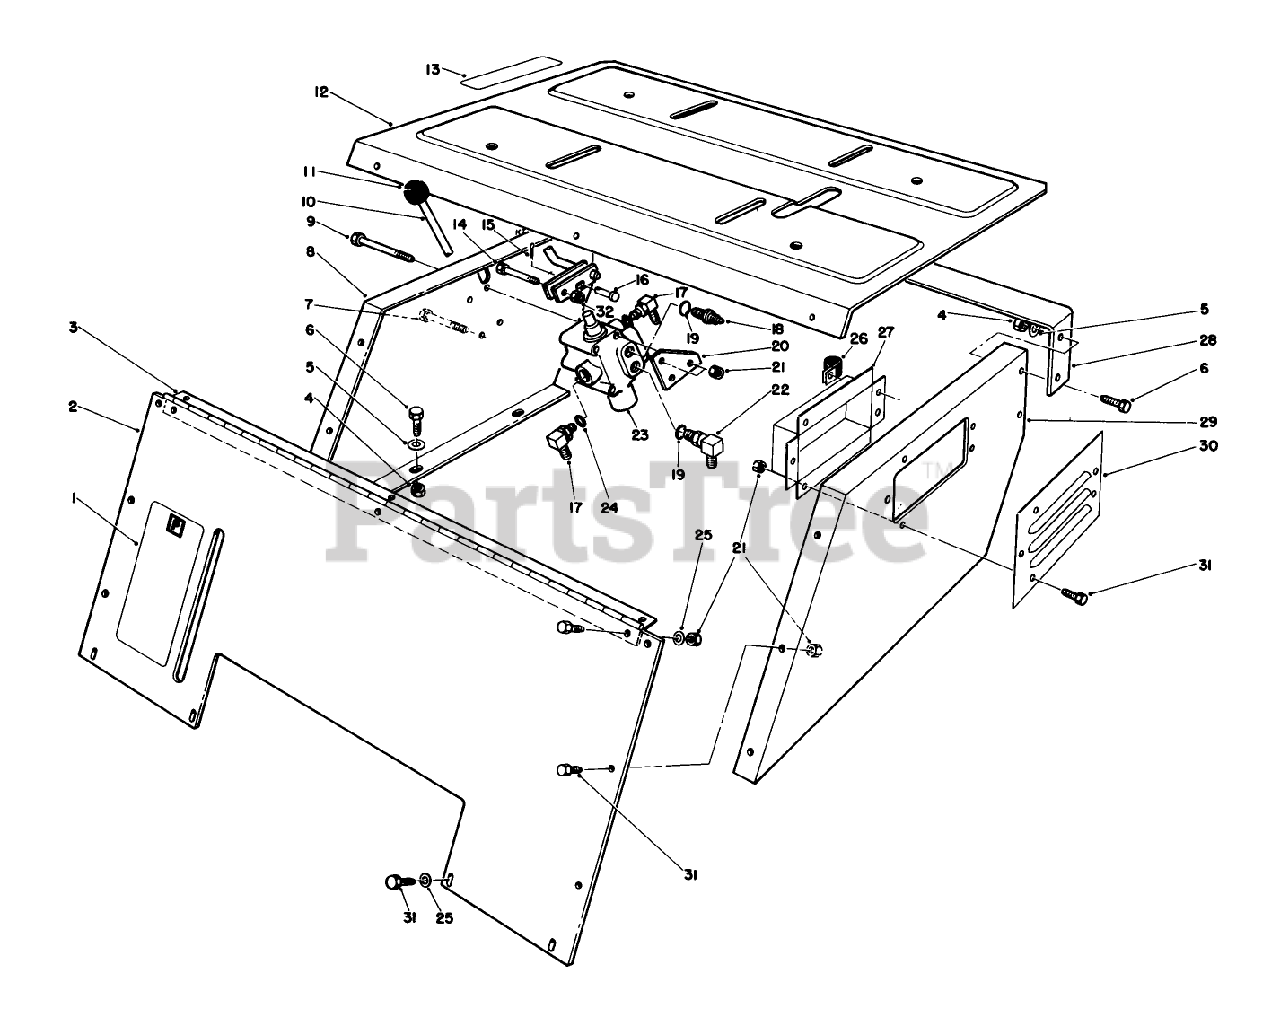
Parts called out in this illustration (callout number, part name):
1	Decal-Parking Brake
4	NUT-LOCK, NI
5	WASHER-PLAIN
6	SCREW-HH
7	SCREW-HH
9	SCREW-HH
12	SEAT PLATE *R
13	LIFT CONTROL DECAL
14	SCREW-HH
15	PIN-COTTER
16	PIN-CLEVIS
17	FITTING-HYD, 90 DEG
18	FITTING-STRAIGHT
19	O-RING
21	NUT-LOCK, NI
22	FITTING-ELBOW, 90
23	VALVE ASM
24	O-RING
25	WASHER-FLAT
26	CLAMP
27	AIR CHAMBER WA *B
31	SCREW-HH
32	NUT-HEX
